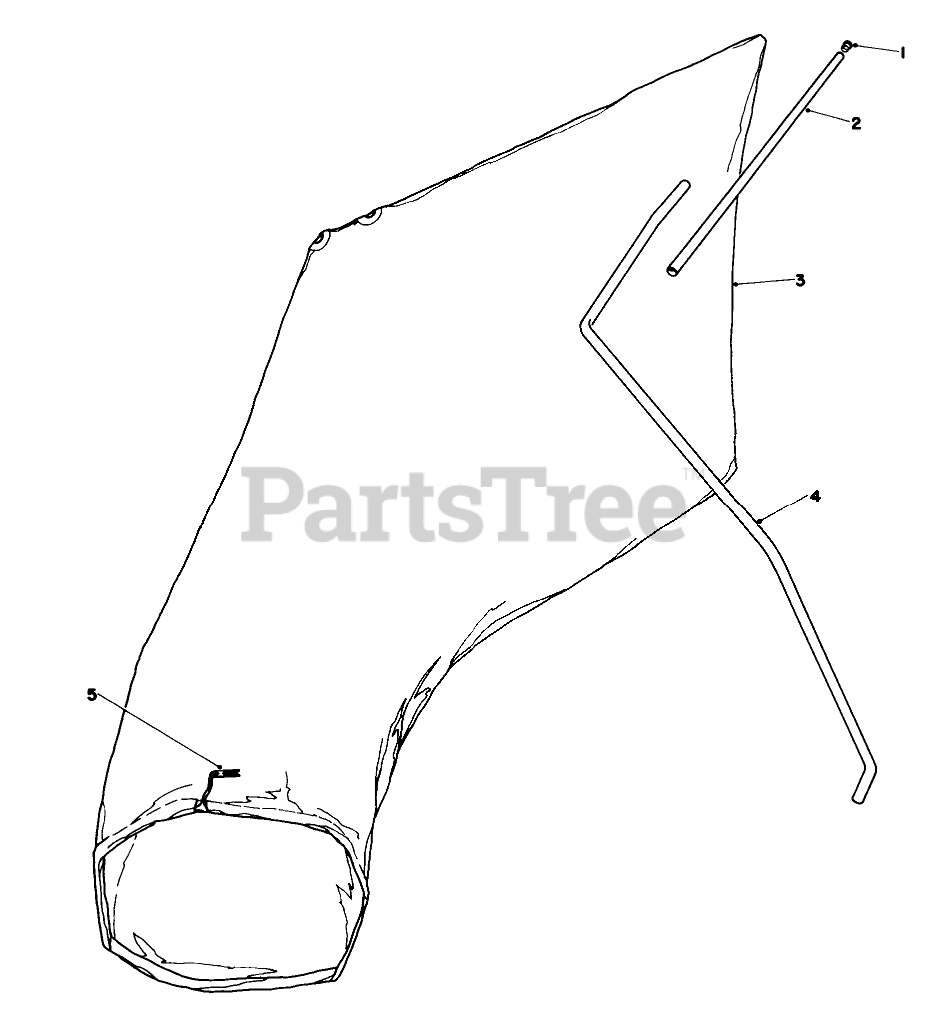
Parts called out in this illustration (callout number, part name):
2	BAG HANGER TUBE
3	Bag (Incl. Ref. #5)
4	HANGER ROD
5	BAG CORD FASTENER
